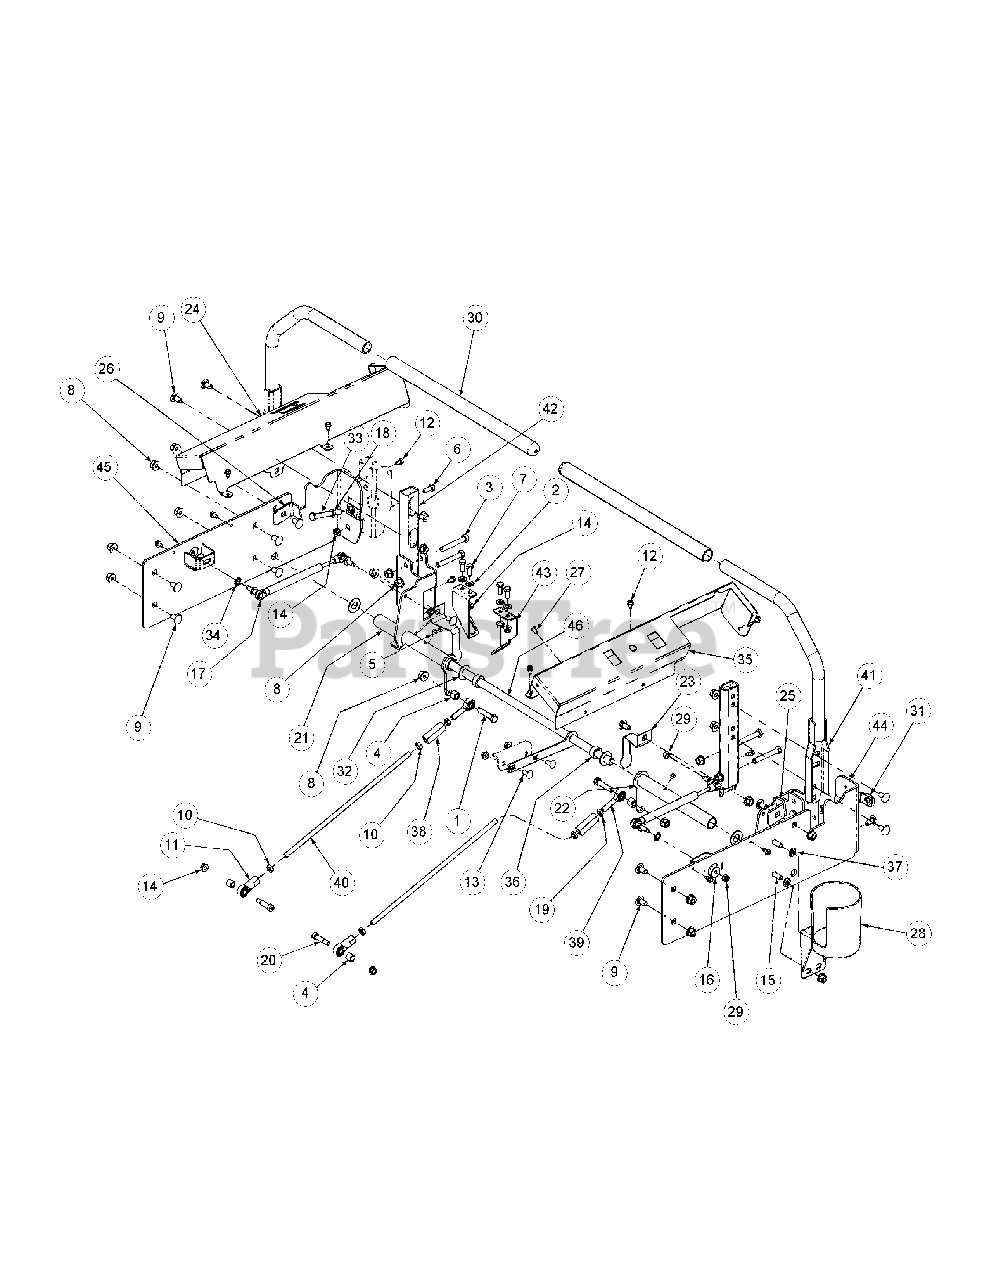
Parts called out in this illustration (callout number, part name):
1	Capscrew, 3/8-16 x 1-3/4
2	Flat Washer, 5/16
3	HHCS, 3/8-16, 2.25
4	Spacer, .625 OD x .385 ID x 1/2
5	Grease Fitting, 90°
6	HHCS, 5/16-18 x 1.0
7	Hex, Cap Screw, 5/16-18 x 3/4
8	Hex Nut, 3/8-16, Lock Flange
9	Carriage Bolt, 3/8-16 x .75
10	Hex Jam Nut, 3/8-24
11	B/Joint, 3/8-24, Right Hand Female
12	Screw, TT, 1/4-20, 0.5, Hex Index Washer
13	Carriage Bolt, 5/16-18 x .75
14	Nut, Lock, HexFlange, 5/16-18
15	Carriage Bolt, 3/8-16 x 1
16	Belle Washer, .325 x .930 x .045
17	Cylinder Return to Neutral
18	Nut, 3/8-16, Jam
19	Nut, 3/8-24, Jam, LH Third
20	Screw, Shoulder Control Rod
21	Hub Assy, Control LH Bearing
22	Hub Assy, Control RH Bearing
23	Lever, Safety Switch
24	Control Panel, LH
27	Screw Button Head, 1/4-20 x .5
28	Cup Holder Assembly
29	Nut, Hex, Center Lock, M8
30	Grip, 1.0
31	U-Nut, 3/8-16, .75
32	Flat Washer, 5/8 Nylon
33	HHCS, 3/8-16, 3.00
34	External Washer, 3/8
35	Control Panel, RH
36	Shaft Collar
37	Push Retainer
38	Turnbuckle
39	B/Joint, 3/8-24, Left Hand Female
40	Rod Connector 3/8 OD x 14.25
41	Lapbar, Handle Assembly
42	Mounting Handle
43	Switch Mounting Bracket, Lapbar
44	Side Panel, Control, Right
45	Side Panel, Control, Left
46	Shaft Control Brake Steering
